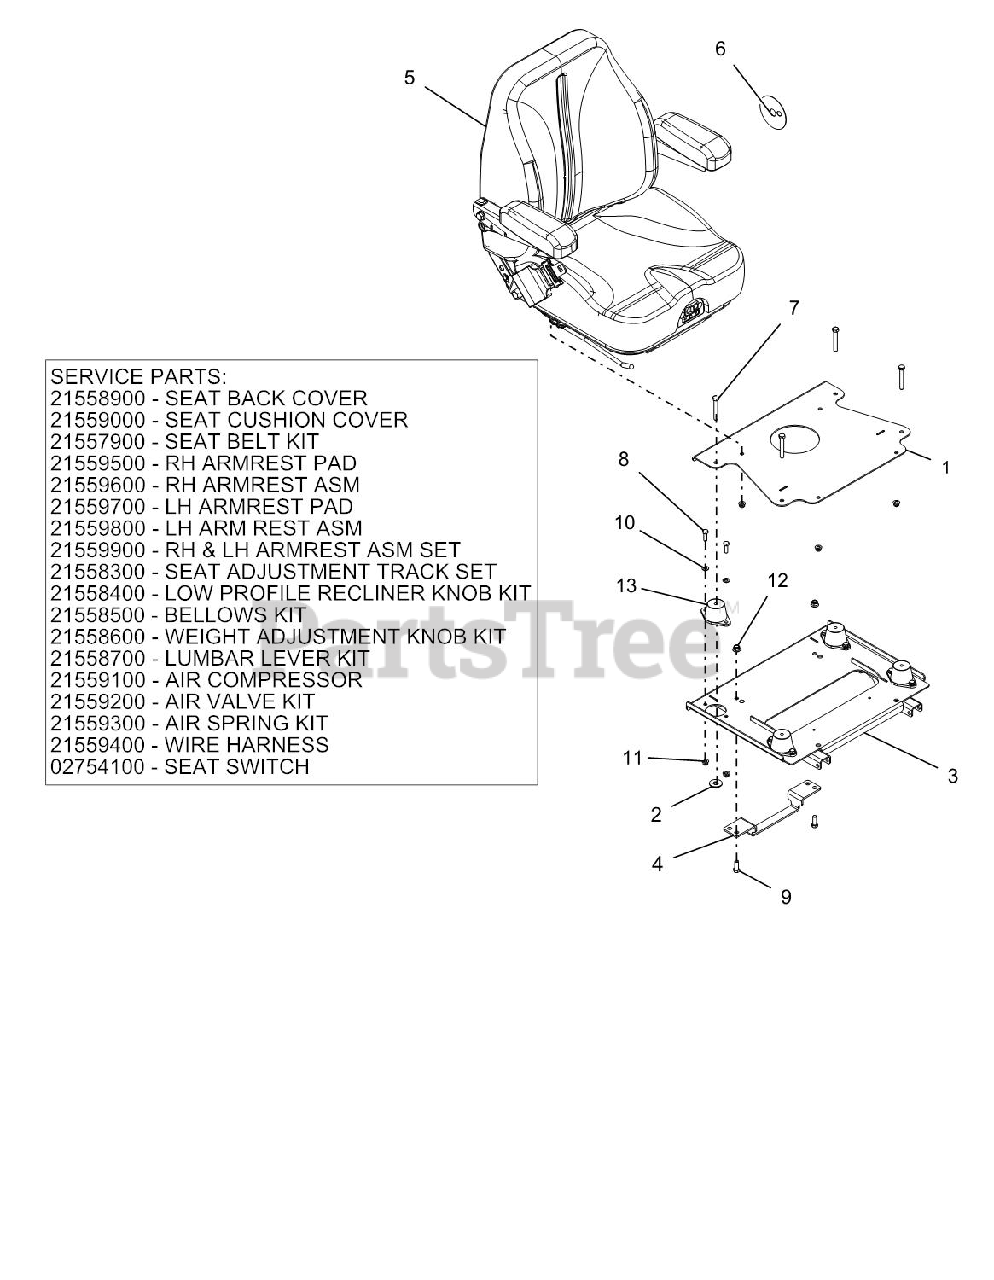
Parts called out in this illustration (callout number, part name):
1	WMT, SEAT PLATE
2	WLDMT, SEAT RETAINER
3	SEAT ISO MTG WMT W/SFTY DECAL
4	BRACKET - SEAT LATCH
5	SWITCH- SNAP MTG N.O.
5	KIT, SEAT BELT
5	SET, SEAT ADJUSTMENT TRACK
5	KIT, LOW PROFILE RECLINER KNOB
5	KIT, BELLOWS
5	KIT, WEIGHT ADJUSTMENT KNOB
5	KIT, LUMBAR LEVER
5	SEAT, AIR SUSPENSION
5	COVER, SEAT BACK
5	COVER, SEAT CUSHION
5	PAD, RH ARMREST
5	ASM, RH ARMREST
5	PAD, LH ARMREST
5	ASM LH ARMREST
5	SET, RH & LH ARMREST ASM
5	COMPRESSOR, AIR RIDE SEAT
5	KIT, AIR VALVE AND LINE
5	KIT, AIR SPRING
5	HARNESS, SEAT WIRE
6	PLATE,DIESEL SET RELCINE LIMIT
7	BLT-HEX .38-16X2.50 FTH YWZC
8	BLT-HEX .31-18X1.00 GR5 YWZC
9	BLT-HEX .38-16X1.00 GR5 YWZC
10	WSHR-FL-STL.344X.688X.065YWZC
11	NUT-LK-NYL-FLG .31-18 YWZC
12	NUT-LK-NYL-FLG .38-16 YWZC
13	MOUNT, ISOLATOR
